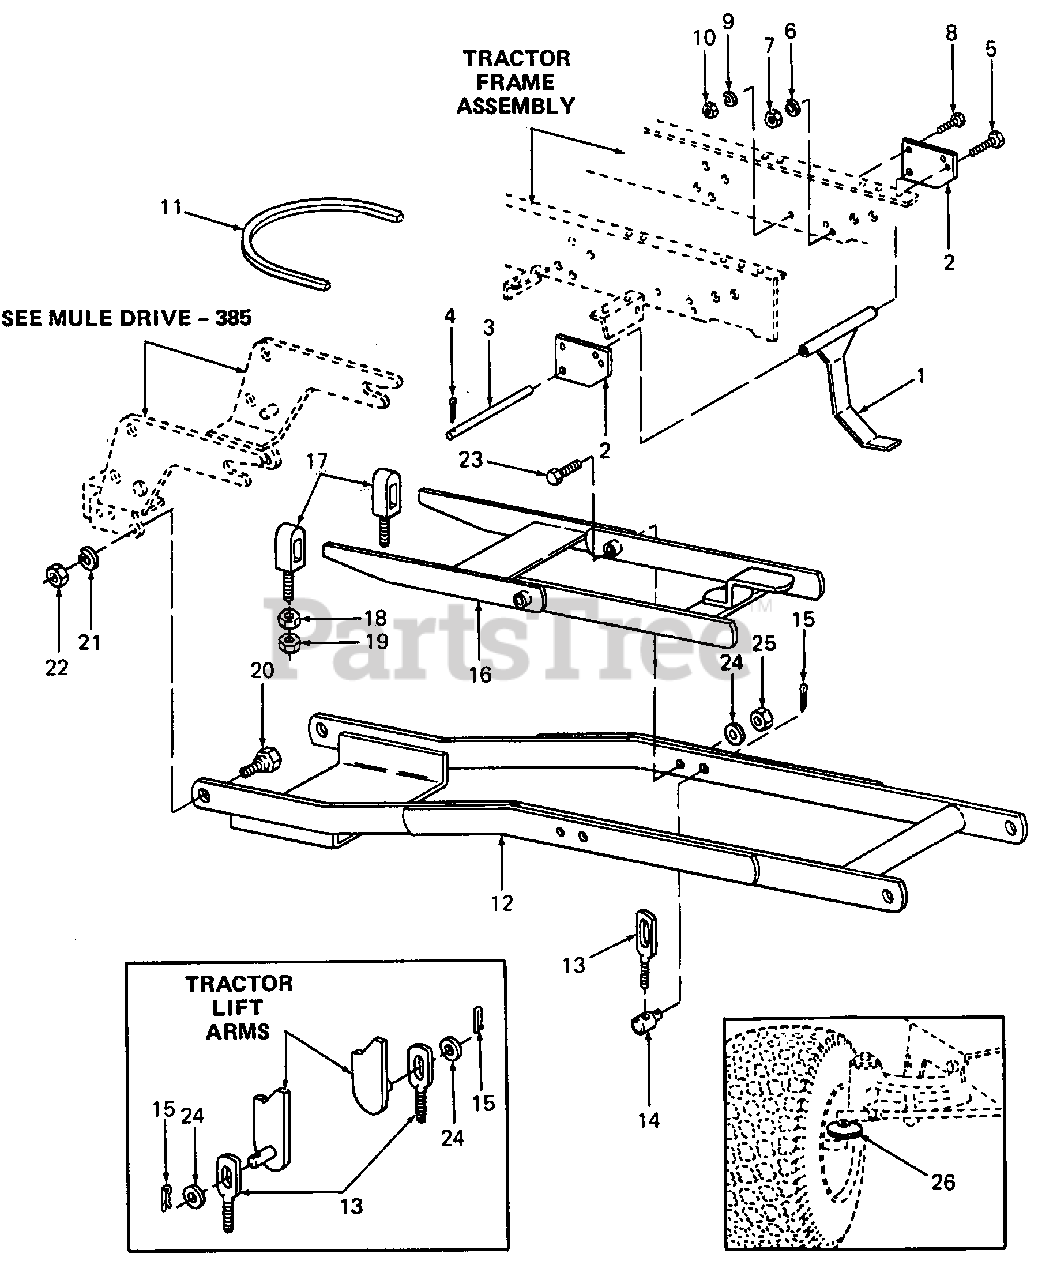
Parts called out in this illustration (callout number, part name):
1	Bar, Rear Stabilizer
2	Plate, Anchor
4	Pin, Quick Attach
5	Screw, Hex Cap, 1/2-13 X 1.75 Lg GR5
6	Washer, Lock, 1/2
7	Nut, Hex, 1/2-13
8	Screw, Hex Cap, 3/8-16 X 1.0 Lg GR5
9	Washer, Lock, 3/8
10	Nut, Hex, 3/8-16
11	Belt, Mule Drive
12	Bracket, Mower Mounting
13	Link, Adjustable
14	Ferrule, Adjustment
15	Pin, Quick Attach
16	Bracket, Mower Lift
17	Hanger, Front Mower Support
18	Nut, Hex Jam, 5/8-11 GR5
19	Nut, Hex Insert Top Lock, 5/8-11 GR5
20	Bolt, Shoulder
21	Washer, Lock, 3/8
22	Nut, Hex, 3/8-16 GR5
23	Screw, Hex Cap, 1/2-13 X 3.0 Lg GR5
24	Washer, Flat, .531 X 1.062 X .074 Thk
25	Nut, Hex Center Lock, 1/2-13 GR5
26	Washer, Wheel Stop
